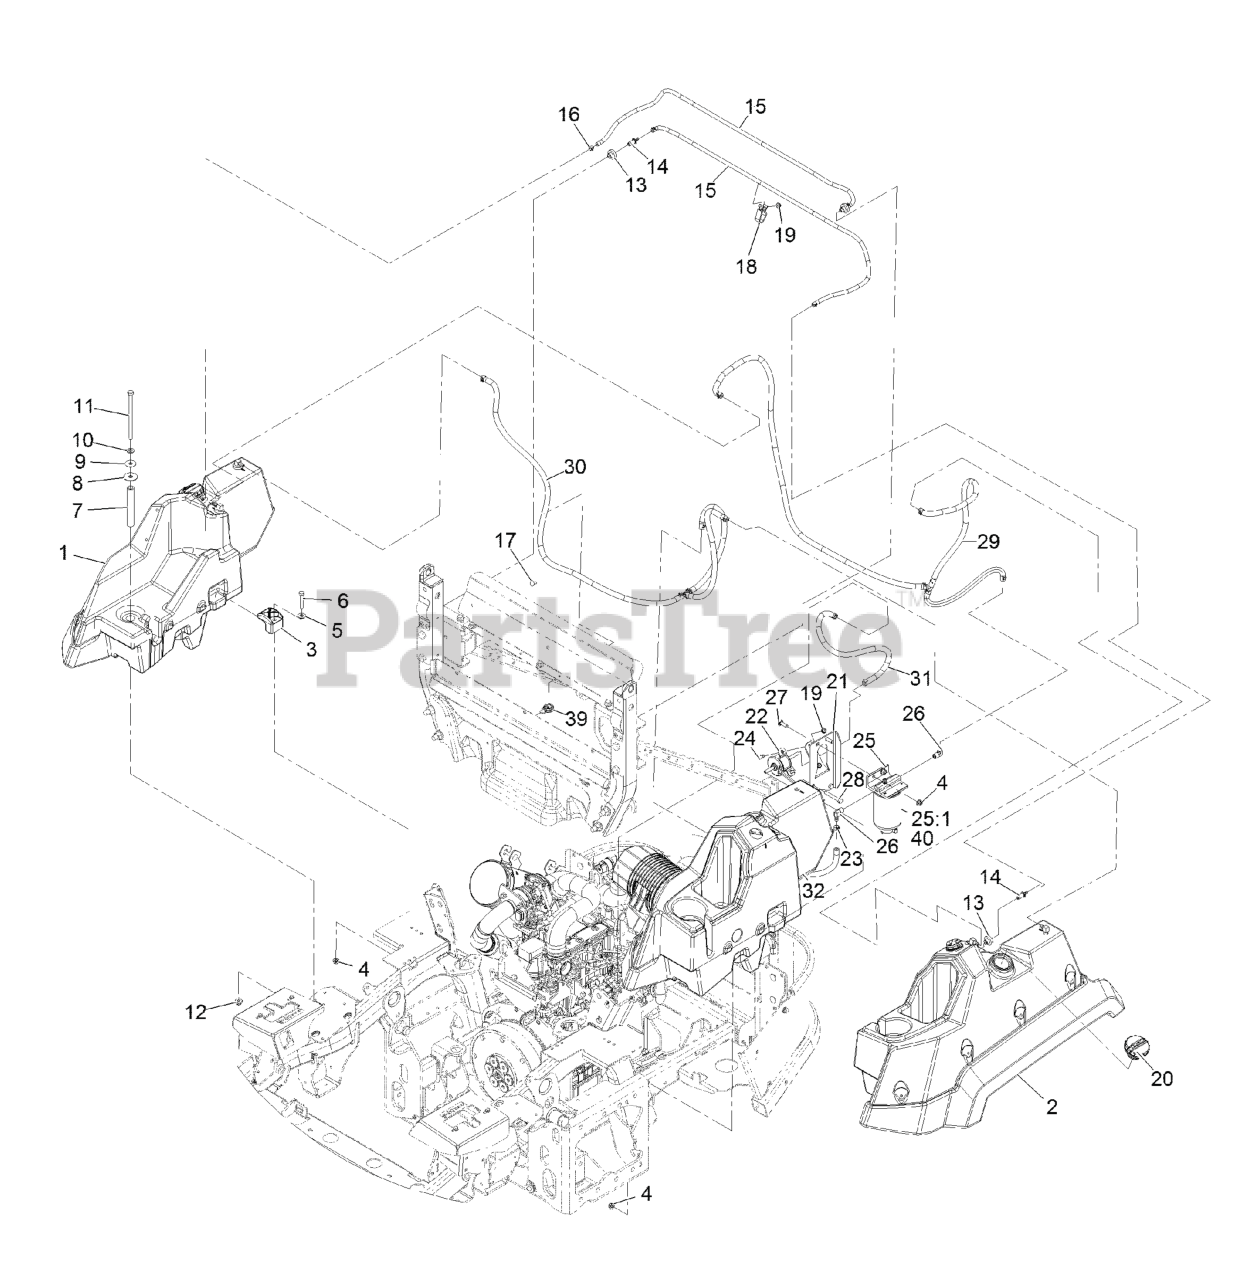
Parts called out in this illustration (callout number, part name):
1	RH FUEL TANK ASM
2	LH FUEL TANK ASM
4	NUT-HF, NI
5	WASHER-FLAT
6	SCREW-HH
7	TUBE-SPACER
8	WASHER-RUBBER
9	WASHER-PLAIN
10	WASHER-FLAT
11	SCREW-HH
12	NUT-HF, NI
13	BUSHING
14	FITTING-ORIFICE, STRAIGHT
15	HOSE-VENT, TANK
16	CLAMP-HOSE
17	SCREW-CARR
18	CLAMP-HOSE
20	CAP-FUEL, DIESEL
21	BRACKET-FILTER AND PUMP,
22	PUMP-FUEL, ELECTRIC
23	CLAMP-HOSE
24	SCREW-HWH
25	Separator-Filter
25	ASM,FUEL FILTER W/HEAD
25:1	FILTER-SPIN ON
26	FITTING-HYD, 90
27	SCREW-CARR
28	SCREW-HH
29	LINE-FUEL, SUCTION
30	LINE-FUEL, RETURN
31	HOSE-FUEL
32	HOSE-FUEL
39	CLIP-TIE
40	FILTER-FUEL
